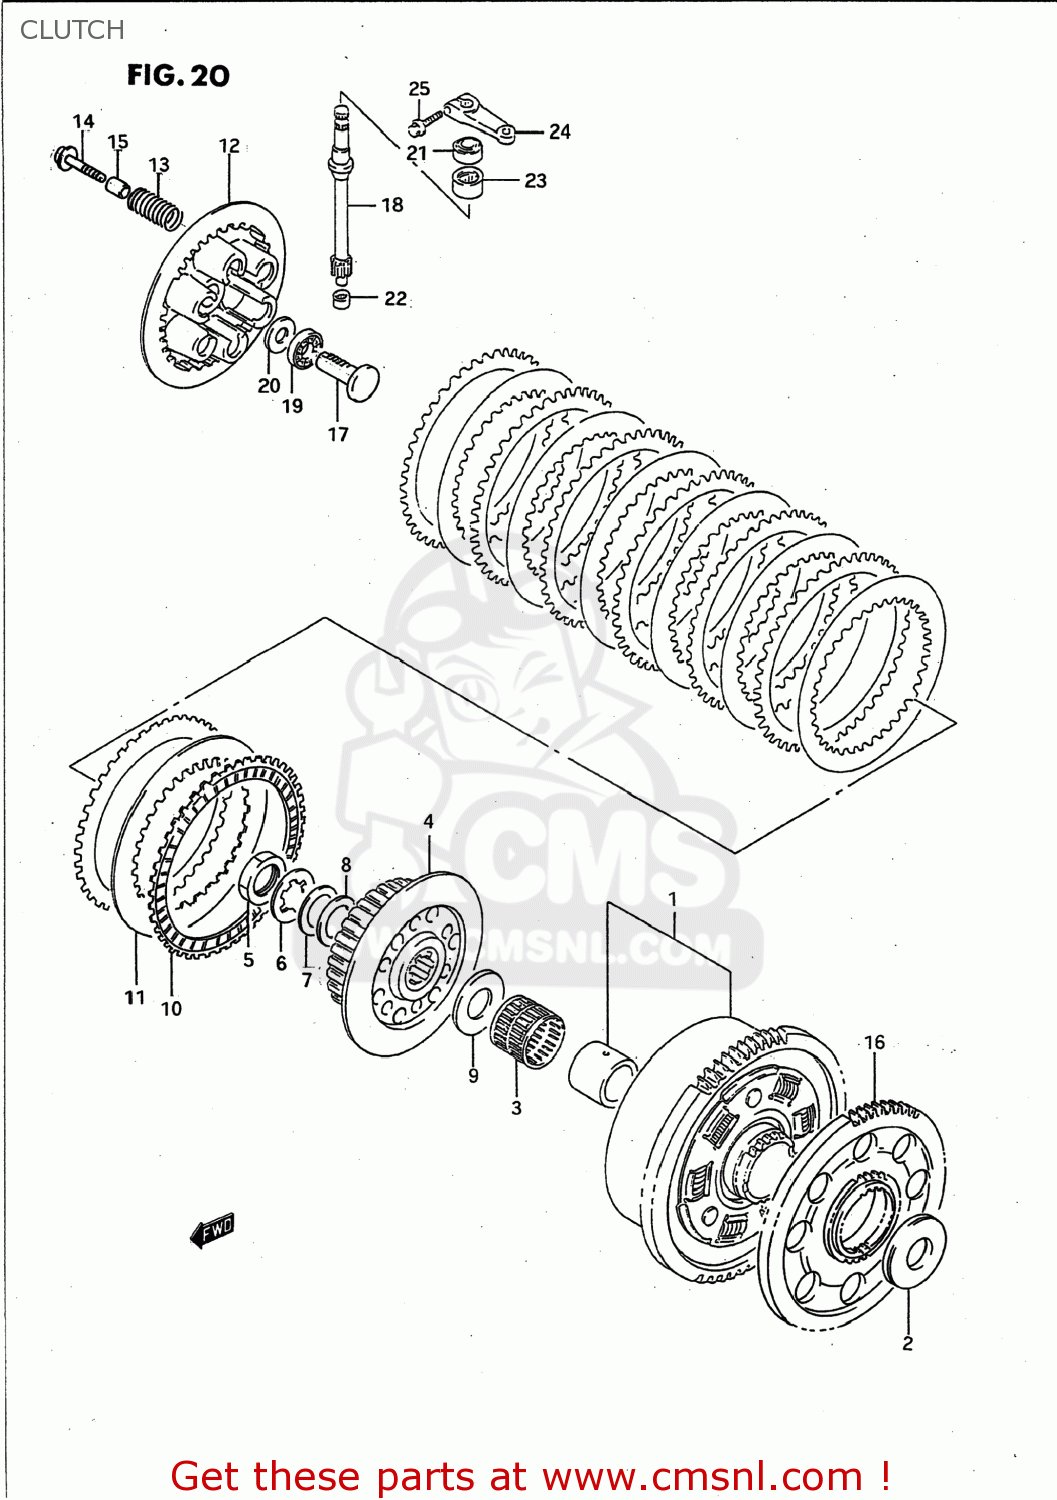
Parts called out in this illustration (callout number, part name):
1	GEAR ASSY,PRI DRIVEN
2	WASHER(25X54X2.5)
3	BEARING(35X40X35.8)
4	HUB,CLUTCH SLEEVE
5	NUT
6	WASHER,LOCK
7	WASHER
8	WASHER
9	WASHER(25X50X2.5)
10	PLATE,CLUTCH DRIVE
11	PLATE,CLUTCH DRIVEN
12	DISC,CLUTCH PRESSURE
13	SPRING
14	BOLT(6X40)
15	SPACER(6.2X12X16)
16	GEAR,GENERATOR DRIVE
17	RACK,CLUTCH RELEASE
18	PINION,CLUTCH RELEASE
19	BEARING(15X28X2)
20	WASHER
21	OIL SEAL
22	BEARING 10X14X10
23	BEARING(15X22X12)
24	ARM,CLUTCH RELEASE
25	BOLT
